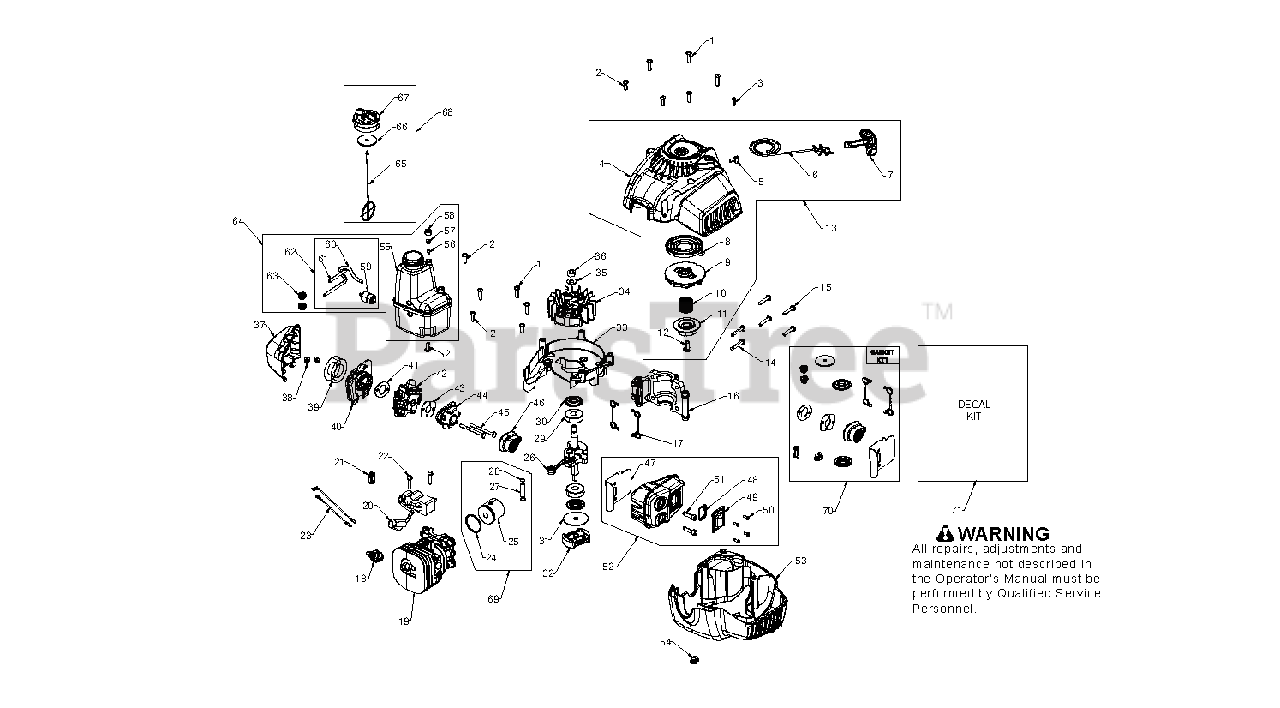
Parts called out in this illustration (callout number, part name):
4	ENGINE HOUSING TOP
5	EYELET, STARTER ROPE
6	ROPE STARTER
7	STARTER HANDLE
8	SPRING STARTER
9	STARTER PULLEY
10	DECAL, WARNING
11	STARTER HUB
13	STARTER HOUSING ASSY
16	BEARING CAP
17	SEAL CYLINDER
18	PLUG SPARK (RCJ6-Y)
19	CYLINDER KIT & F'WHEEL SCROLL
20	IGNITION MODULE
22	SCREW M4 X .70 TT 16MM
23	WIRE COIL
24	RING PISTON
26	CRANKSHAFT ASSY
27	PISTON PIN
28	WRIST PIN RET.
29	Radial Ball Bearing, 6201
30	CRANKSHAFT SEAL
31	GASKET, CLUTCH
32	CLUTCH KIT
33	CYLINDER KIT & F'WHEEL SCROLL
34	FLYWHEEL ASSY
36	NUT-FLYWHEEL
37	AIR FILTER COVER
41	GASKET AIRBOX
42	CARBURETOR KIT
43	GASKET CARB
44	CARB PLATE
46	Carburetor Boot
48	SPARK ARRESTOR SCREEN
49	HOOD EXHAUST OUTLET
51	BOLT MUFFLER
52	MUFFLER ASSY
53	ENGINE HOUSING, LOWER
55	FUEL TANK
58	VALVE COVER
59	FUEL FILTER
60	FUEL TUBE INLET
61	FUEL TUBE OUTLET
62	FUEL LINE KIT
63	FUEL TUBE GROMMET
64	FUEL TANK ASSY
65	RETAINER
67	FUEL CAP
68	FUEL CAP ASSY
69	PISTON KIT
70	GASKET KIT
71	DECAL KIT
